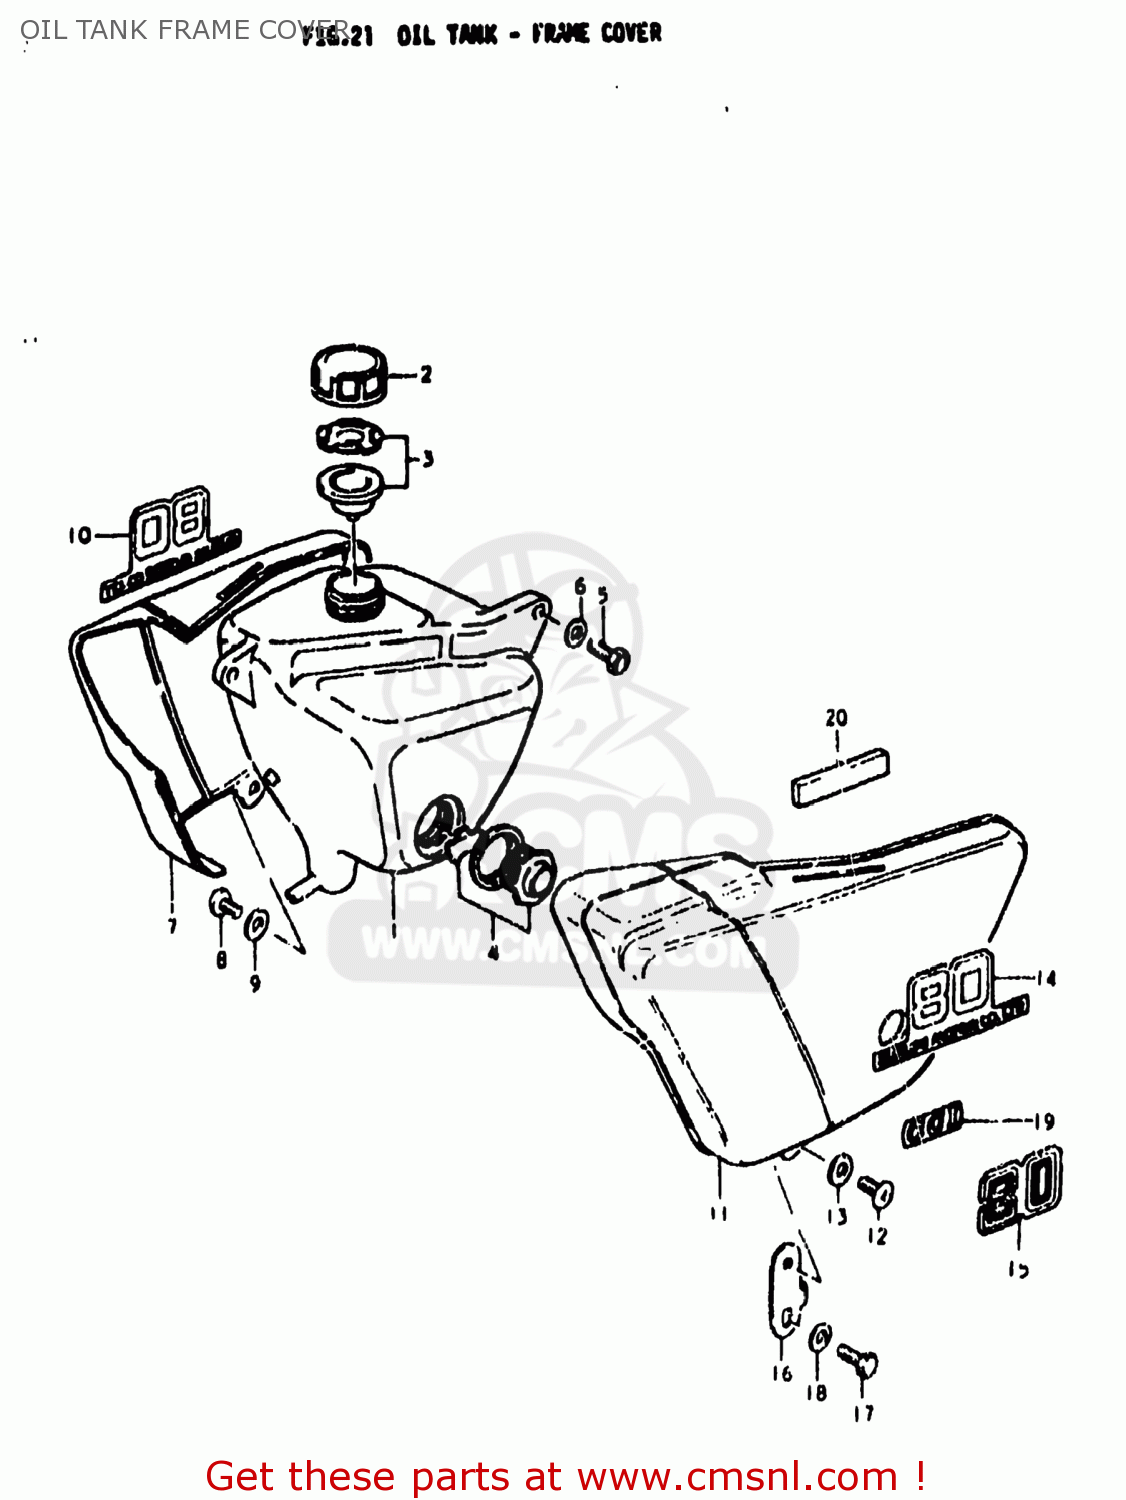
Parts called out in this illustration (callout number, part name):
1	TANK,OIL
2	CAP,OIL TANK
3	GASKET SET (NAS)
4	LENS SET,OIL LEVEL
5	BOLT, UPPER
6	WASHER
7	COVER,FRAME,RIGHT
8	SCREW 6X12
9	WASHER
10	EMBLEM
11	COVER,FRAME,LEFT
12	SCREW 6X12
13	WASHER
14	EMBLEM
15	EMBLEM
16	PLATE,FRAME COVER
17	BOLT
18	WASHER 6MM
19	EMBLEM,CCIS
20	CUSHION,FRAME COVER
